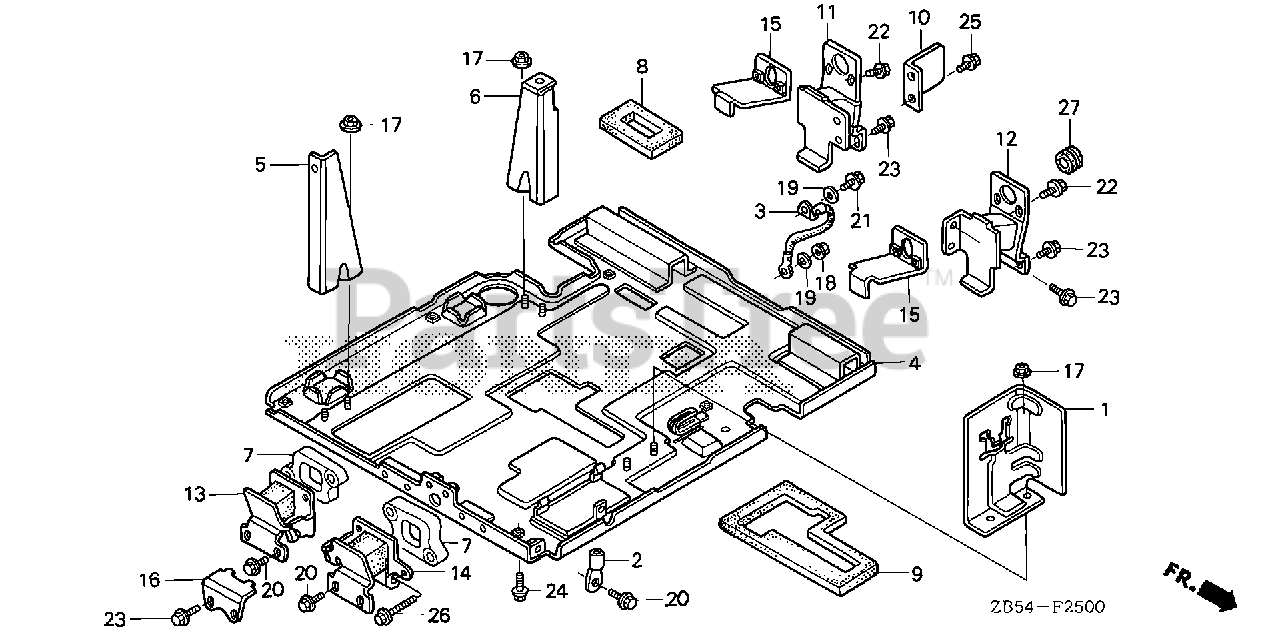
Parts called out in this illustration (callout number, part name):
1	SUPPORT, RESERVE TANK
2	TERMINAL, LA (8MM)
3	WIRE, GROUND
4	BED, FRAME
5	STAND, R. SHROUD
6	STAND, L. SHROUD
7	SPACER, GENERATOR MOUNTING
8	SEAL, MOTOR STAY
9	SEAL, FR. HOUSING
10	STOPPER, ENGINE MOUNT SIDE
11	RUBBER, R. FR. MOUNT
12	RUBBER, L. FR. MOUNT
13	RUBBER, R. RR. MOUNT
14	RUBBER, L. RR. MOUNT
15	STOPPER, ENGINE MOUNT RUBBER
16	STOPPER, GENERATOR MOUNT
17	NUT, FLANGE (6MM)
18	NUT, FLANGE (8MM)
19	WASHER, STAR
20	BOLT, FLANGE (8X16)
21	BOLT, FLANGE (8X20)
22	BOLT, FLANGE (6X16)
23	BOLT, FLANGE (8X16)
24	BOLT, FLANGE (8X16)
25	BOLT, FLANGE (8X25)
26	BOLT, FLANGE (8X45)
27	RUBBER B, STEP MOUNTING
